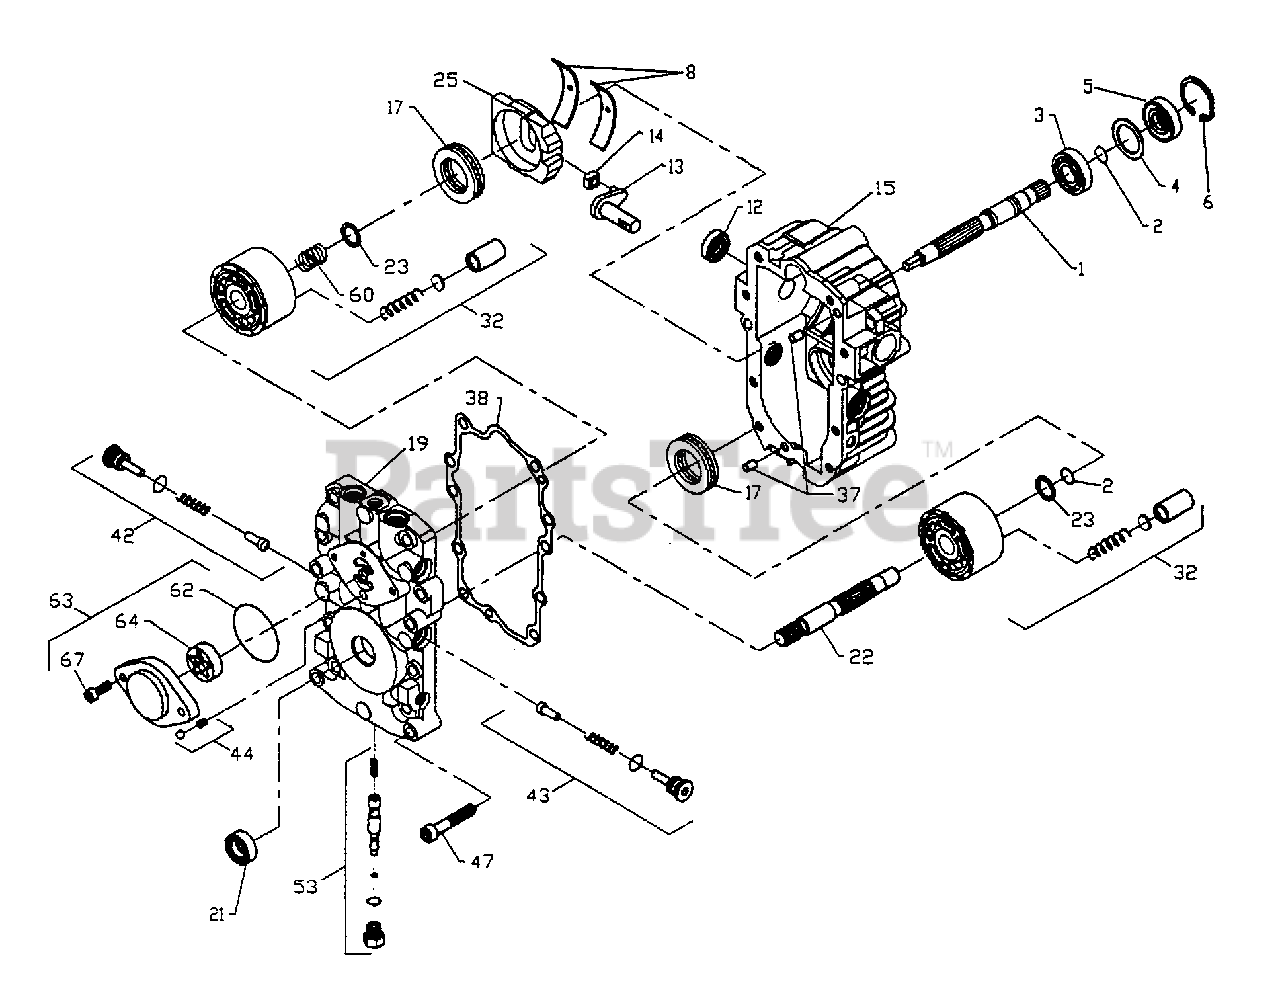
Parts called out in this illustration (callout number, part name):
1	SHAFT.PUMP.50158
2	RETAINIANG RING-(2003016)
3	BALL BEARING
4	SPACER
5	SEAL LIP
6	RING.RET.2003052
8	CRADLE BEARING (2003023)
12	SEAL.9008000-0126
13	TRUNION ARM (2003005)
14	GUIDE.2000015.HYD
15	KIT.HSG.2513035.
19	KIT.CENT.2513006
21	LIP SEAL-9008000-0127
22	SHAFT.MOT.2003034
23	WASHER.2003017
25	"SWASHPLATE,VARIAB"
32	BLOCK.CLYN.70079.
37	PIN
38	GASKET.20030600
42	KIT.VALVE.2510050
43	KIT.VALVE.2510050
44	KIT.RELI.2510011.
47	SCREW9007314-0808
53	"KIT,BYPASS VALVE"
60	SPRING.2003014.
62	0RING.90041011340
63	KIT.CHARG.2513027
64	GEROTOR.J1041008
67	SCREW.CAP.50095.
